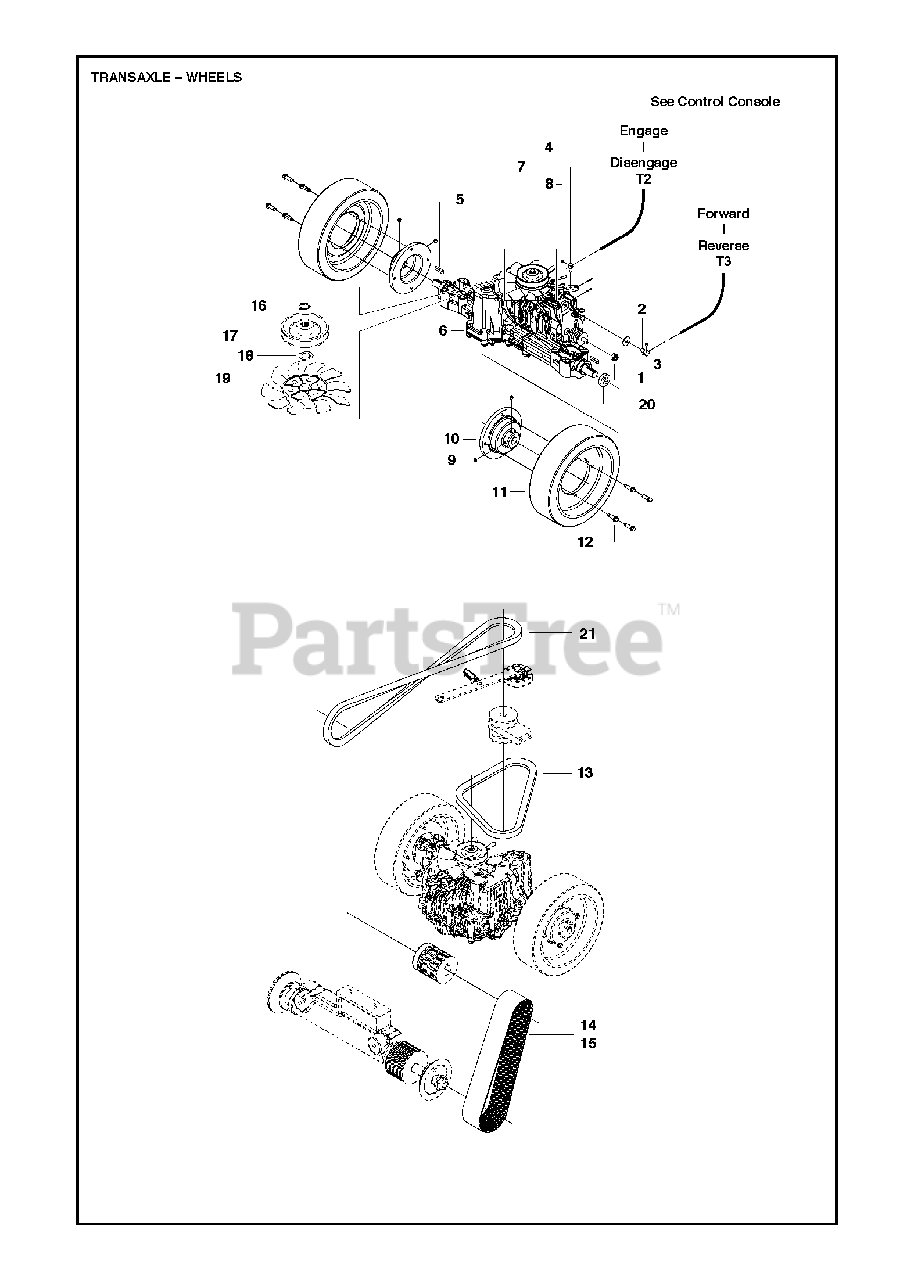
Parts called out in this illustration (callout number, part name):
1	HEXAGON LOCKING NUT
3	WASHER
6	TRANSAXLEValid until serial number 2016 1300008
6	TRANSAXLEValid from serial number 2016 1300009
14	BELTFS 513 -18&20”
15	BELTFS 520 - 20”, FS 524 - 24”
16	SPRING WASHER
20	SEALING
